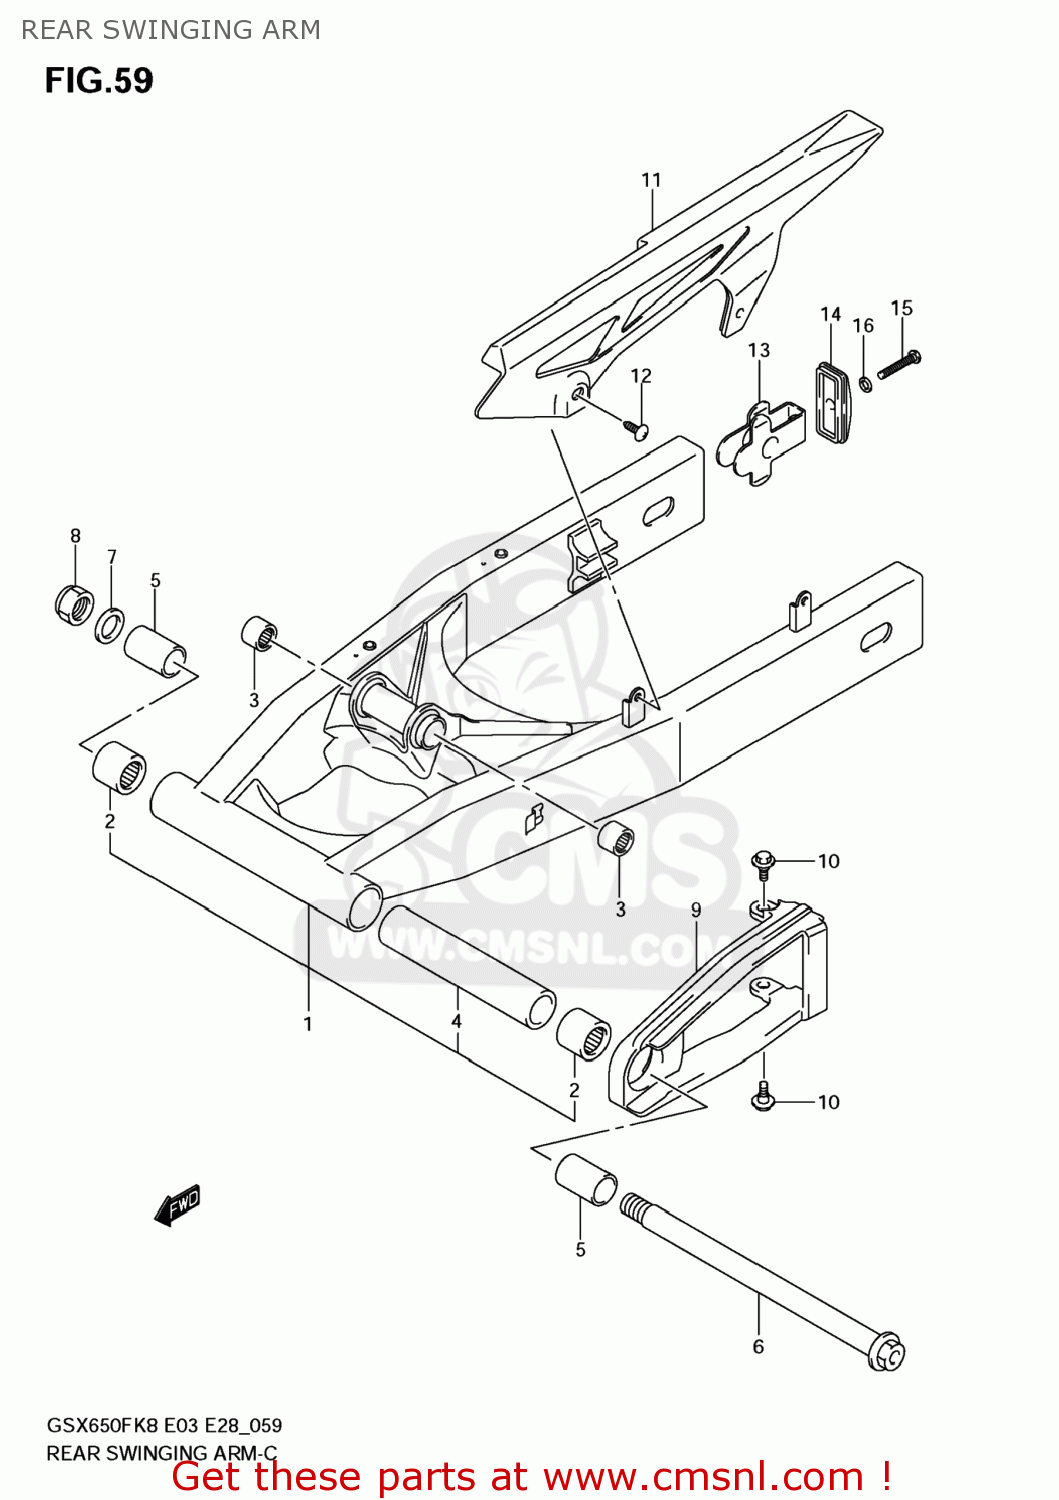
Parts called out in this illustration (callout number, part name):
1	SWINGINGARM ASSY,RR
2	BEARING(25X33X35)
3	BEARING(17X24X25)
4	SPACER(20.8X27.2X146)
5	SPACER,RR SWGARM PIVOT
6	SHAFT,RR SWINGINGARM PIVOT
7	WASHER(18.5X28X2.6)
8	NUT
9	BUFFER,CHAIN TOUCH DEFENSE
10	BOLT(6X17.8)
11	CASE,CHAIN
12	SCREW(6X16)
13	ADJUSTER,CHAIN
14	PLATE,CHAIN ADJUSTER GUIDE
15	BOLT(8X50)
16	WASHER
